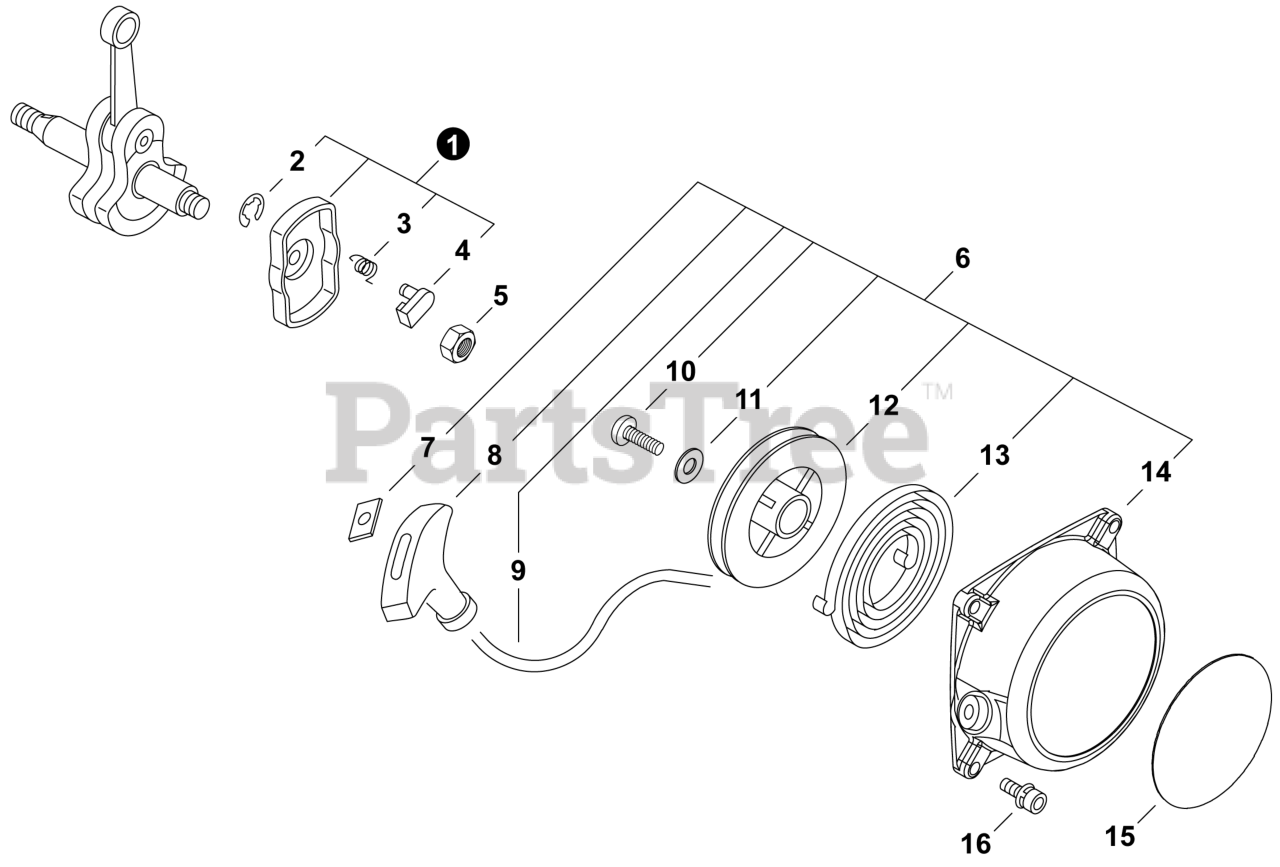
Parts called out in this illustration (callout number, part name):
1	PAWL ASSY, STARTER
2	E-RING 4
3	SPRING, RETURN
4	PAWL, STARTER
5	NUT 8x1.25
6	STARTER ASSY
7	RETAINER, ROPE
8	GRIP, STARTER
9	ROPE, STARTER 4.0x880
12	REEL, ROPE
13	SPRING, RECOIL
14	CASE, STARTER
15	LABEL - RECOIL STARTER
16	BOLT 4x20
